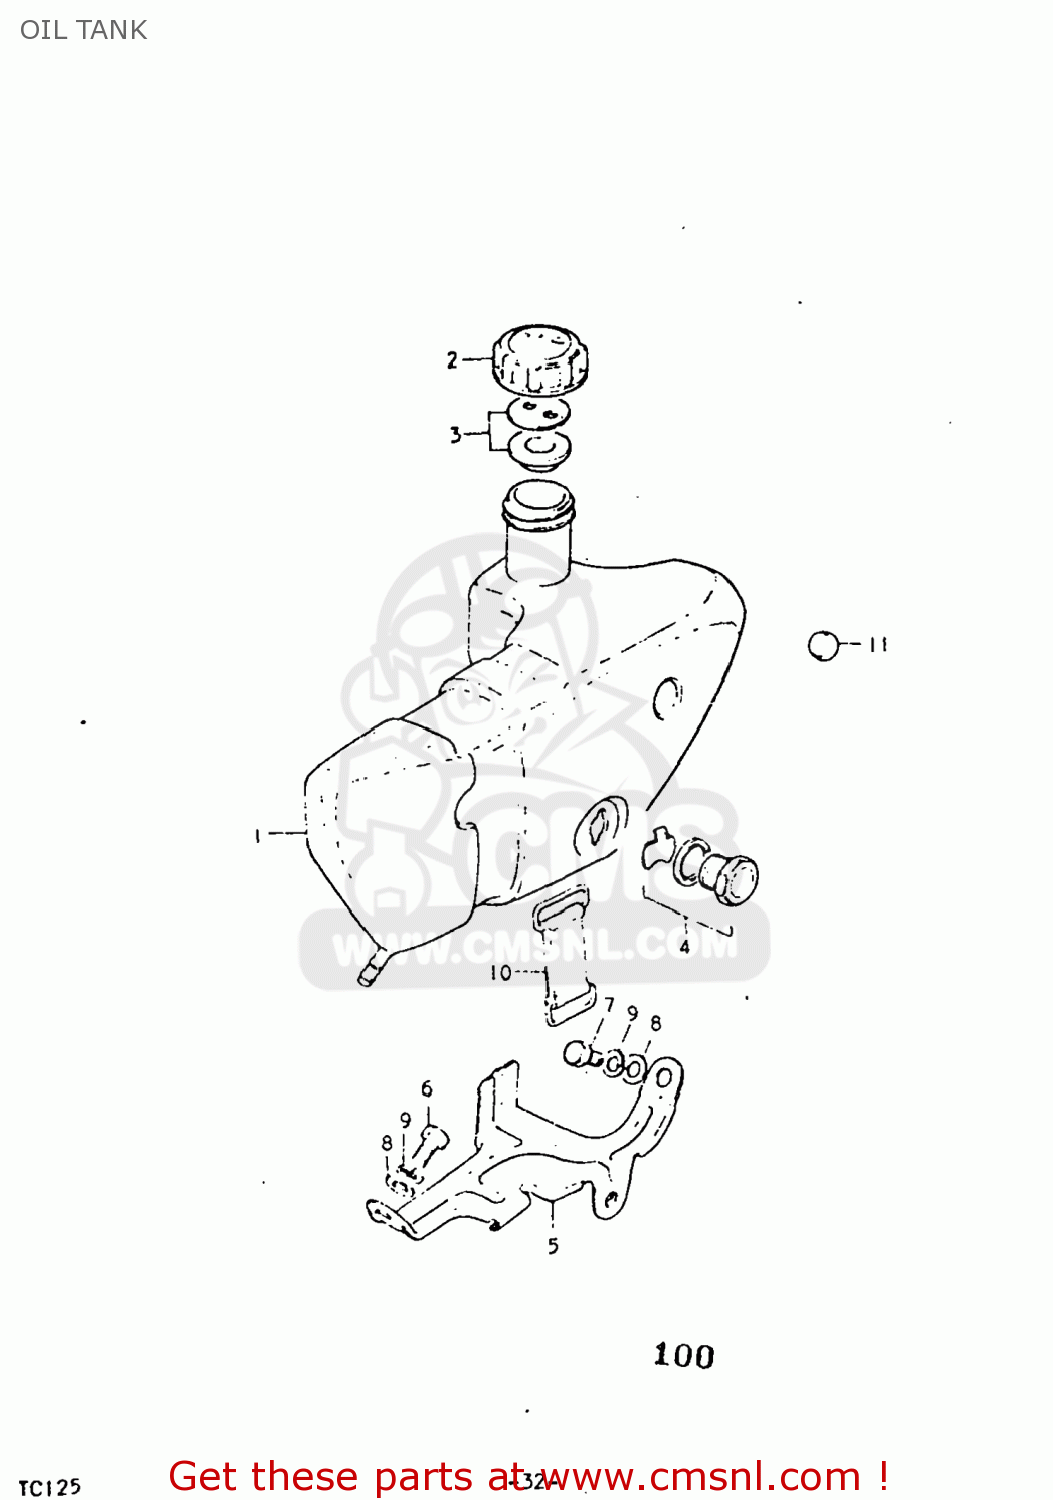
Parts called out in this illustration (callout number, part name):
1	TANK,OIL
2	CAP,OIL TANK
3	LENS,OIL LEVEL INSPECTION
4	LENS SET,OIL LEVEL
6	BOLT
7	BOLT
8	WASHER
9	LOCK WASHER
10	BAND
11	CUSHION
